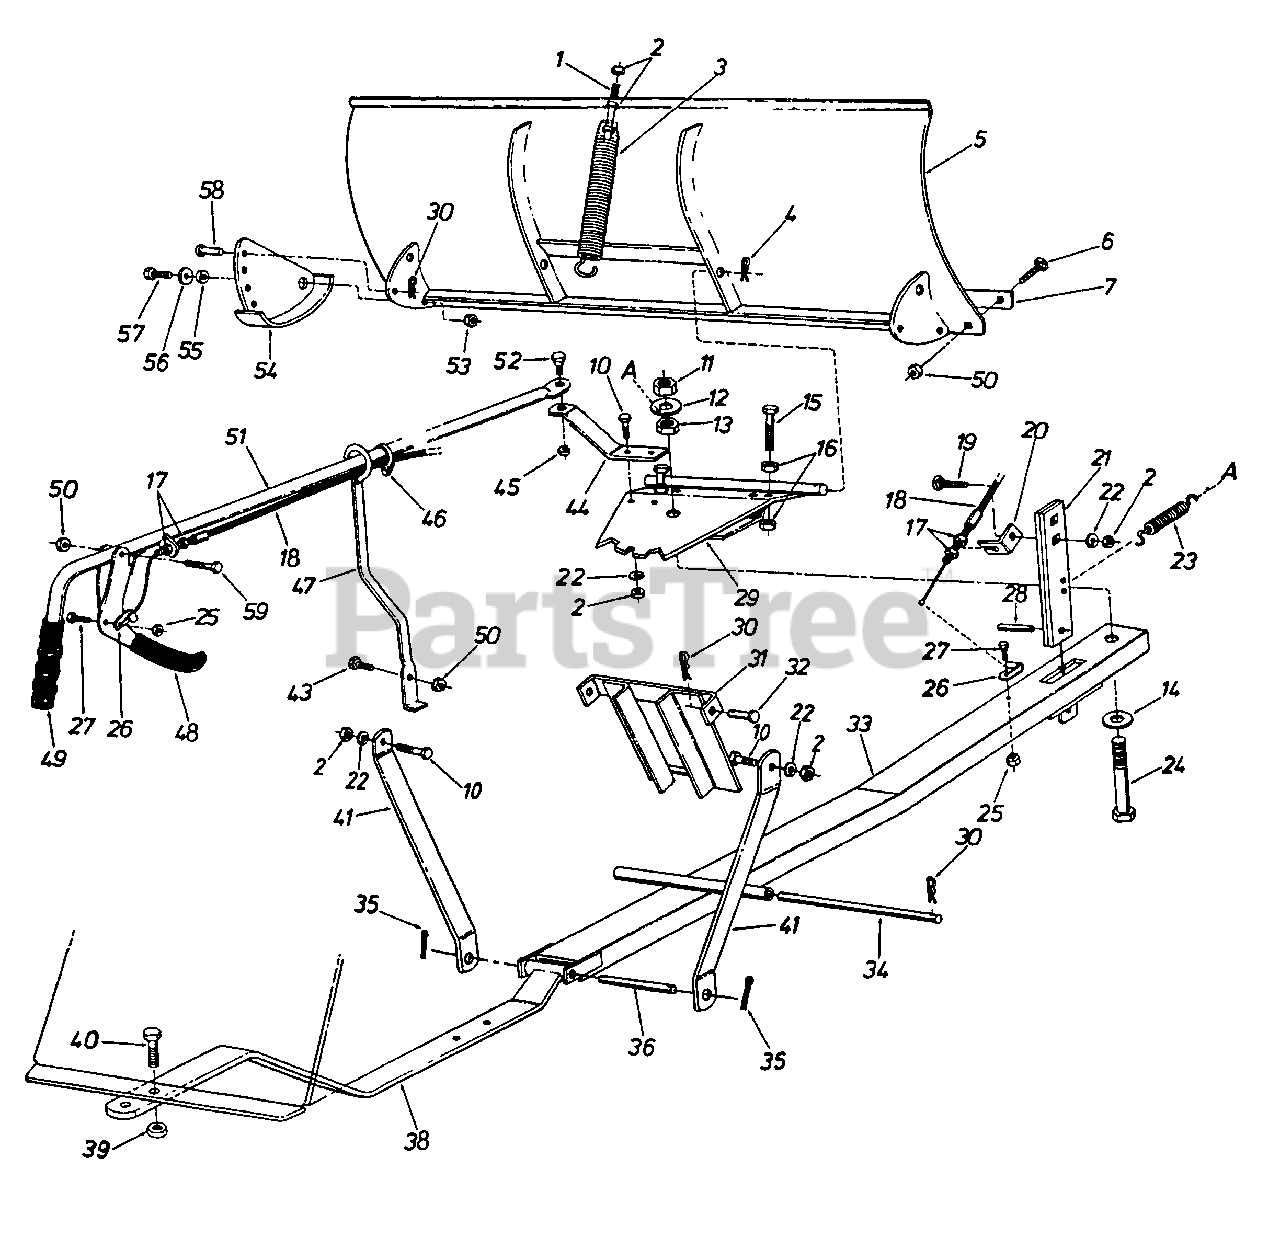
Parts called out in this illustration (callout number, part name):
1	Hex Bolt 3/8-16 x 4.5" Lg.
2	Hex Nut 3/8-16 Thd.
3	Blade Adjustment Spring
4	Hairpin Clip 5/32" Dia.
5	48" Blade Ass'y.
6	Carriage Bolt 5/16-18 x .75" Lg.
7	Wear Plate 48"
10	Hex Bolt 3/8-16 x 1.0" Lg.
11	Hex L-Nut 3/4-10 Thd.
12	Fl-Wash. .81" I.D. x 2.0" O.D. (Special)
13	Hex Jam Nut 3/4-10 Thd.
14	Fl-Wash. .81" I.D. x 2" O.D.
15	Hex Bolt 1/2-13 x 2.0" Lg.
16	Hex Nut 1/2-13 Thd.
17	Hex Jam Nut 5/16-24 Thd.
18	Control Cable Ass'y.
19	Carriage Bolt 3/8-16 x 1.25" Lg.
20	Cable Guide Bracket
21	Angle - Lock Bar
22	L-Wash. 3/8" I.D.
23	Angle Lock Spring
24	Hex Scr. 3/4-10 x 4.0" Lg. (Special)
25	Hex L-Nut 1/4-20 Thd.
26	Clevis Lanyard Fitting
27	Hex Bolt 1/4-20 x .75" Lg.
28	Roll Pin 1/4" Dia. x 1.0" Lg.
29	Pivot Plate Ass'y.
30	Hairpin Clip 3/32" Dia.
31	Guide Bracket Ass'y.
32	Clevis Pin 1/2" Dia. x 1.0" Lg.
33	Push Bar Ass'y.
34	Lift Shaft
35	Cotter Pin 5/32" Dia. x 1.0" Lg.
36	Pivot Shaft
38	Hanger Bracket Ass'y.
39	Hex L-Nut 5/8-11 Thd.
40	Hex Bolt 5/8-11 x 1.5" Lg.
41	Hanger Link
43	Hex Bolt 5/16-18 x 1.0" Lg.
44	Blade Pivot Bracket
45	Hex L-Nut 3/8-16 Thd.
46	Nylon Cable Tie
47	Tube Guide Ass'y.
48	Clutch Grip Ass'y.
49	Grip - 3/4" Handle
50	Hex L-Nut 5/16-18 Thd.
51	Tube Handle Ass'y.
52	Shld. Bolt - Special 3/8-16 Thd.
53	Hex L-Nut 3/8-16 Thd.
54	Skid Assembly
55	Spacer
56	Fl-Wash. .385" I.D. x 1.0" O.D.
57	Hex Bolt 3/8-16 x 4.75" Lg.
58	Clevis Pin 5/16" Dia. x .75" Lg.
59	Hex Bolt 5/16-18 x 1.5" Lg.
